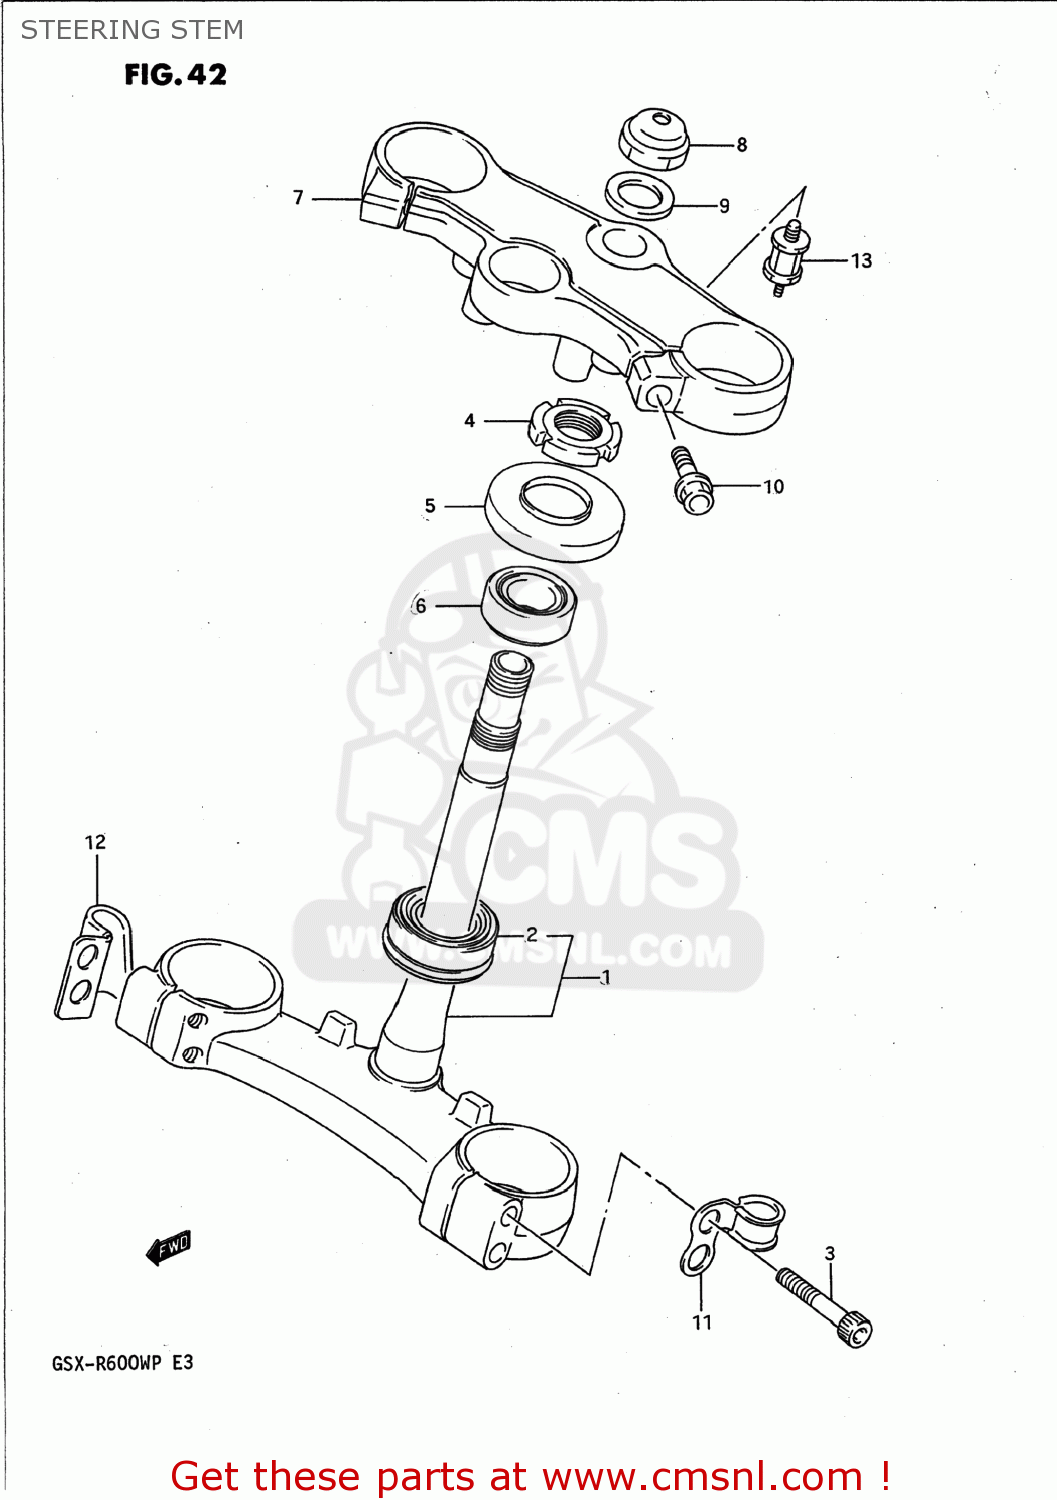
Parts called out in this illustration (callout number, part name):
1	STEM,STEERING
2	BEARING(30X55X17)
3	BOLT 10X45
4	NUT,STEERING STEM(25X44X10)
5	SEAL OIL
6	TAPER,ROLLER BEARING
7	HEAD,STEERING STEM
8	NUT,STEM HEAD
9	WASHER
10	BOLT
11	GUIDE,SPEEDOMETER CABLE
12	CLAMP,CLUTCH CABLE
13	BOLT,SPEEDOMETER CUSHION
